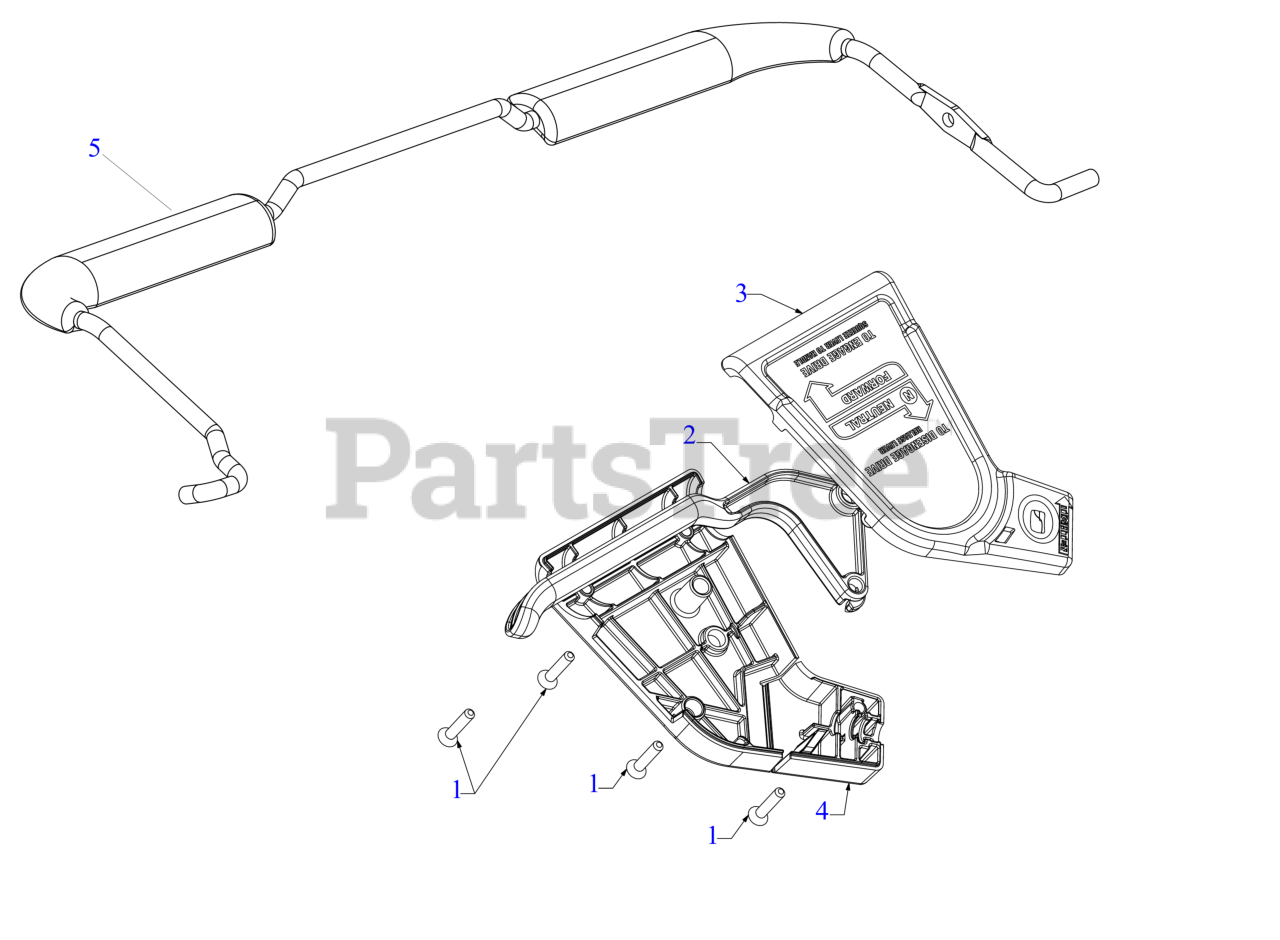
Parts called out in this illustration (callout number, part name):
1	SCREW #10-16 x .750
2	ENGAGEMENT LEVER
3	KIT-DRIVE CONTROL
4	SQUEEZEBOX CONTROL COVER
5	OPERATOR BAIL ASSEMBLY
